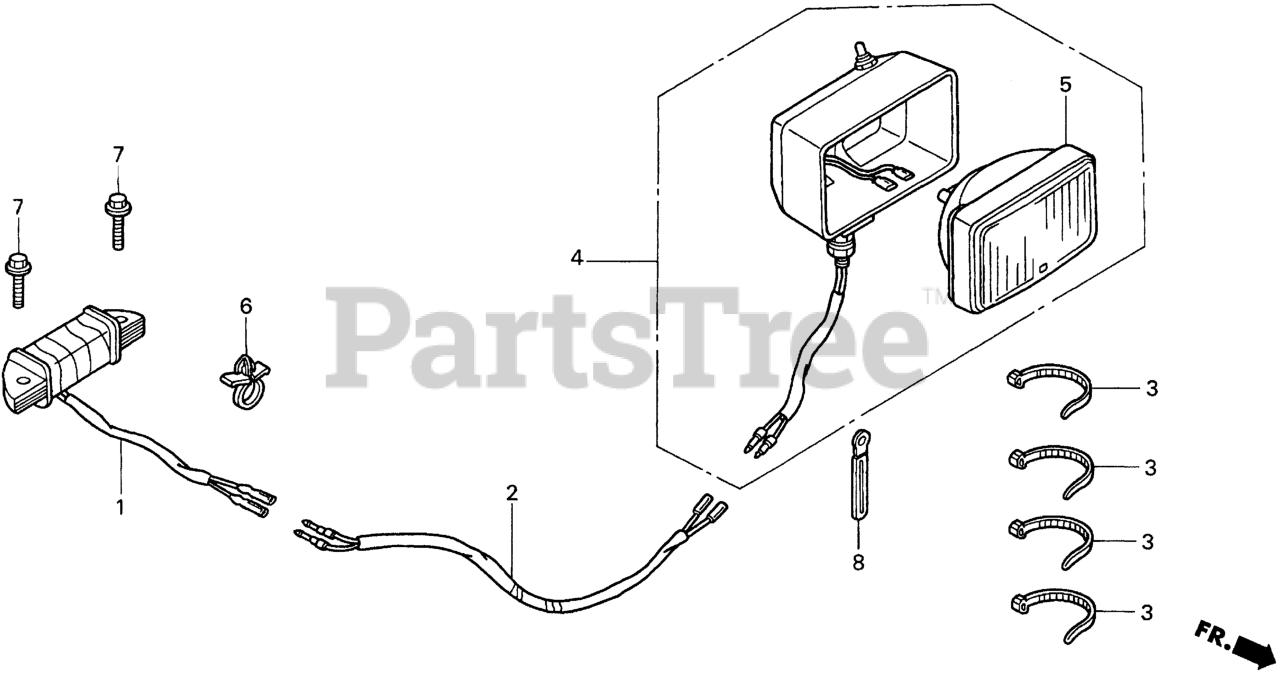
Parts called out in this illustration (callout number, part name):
1	COIL ASSY., LAMP
2	SUB-HARNESS, HEADLIGHT
3	TIE, CABLE
4	HEADLIGHT ASSY.
5	SEALED BEAM UNIT
6	CLIP A, WIRE
7	BOLT, FLANGE (6X32)
8	CLIP, WIRE HARNESS
